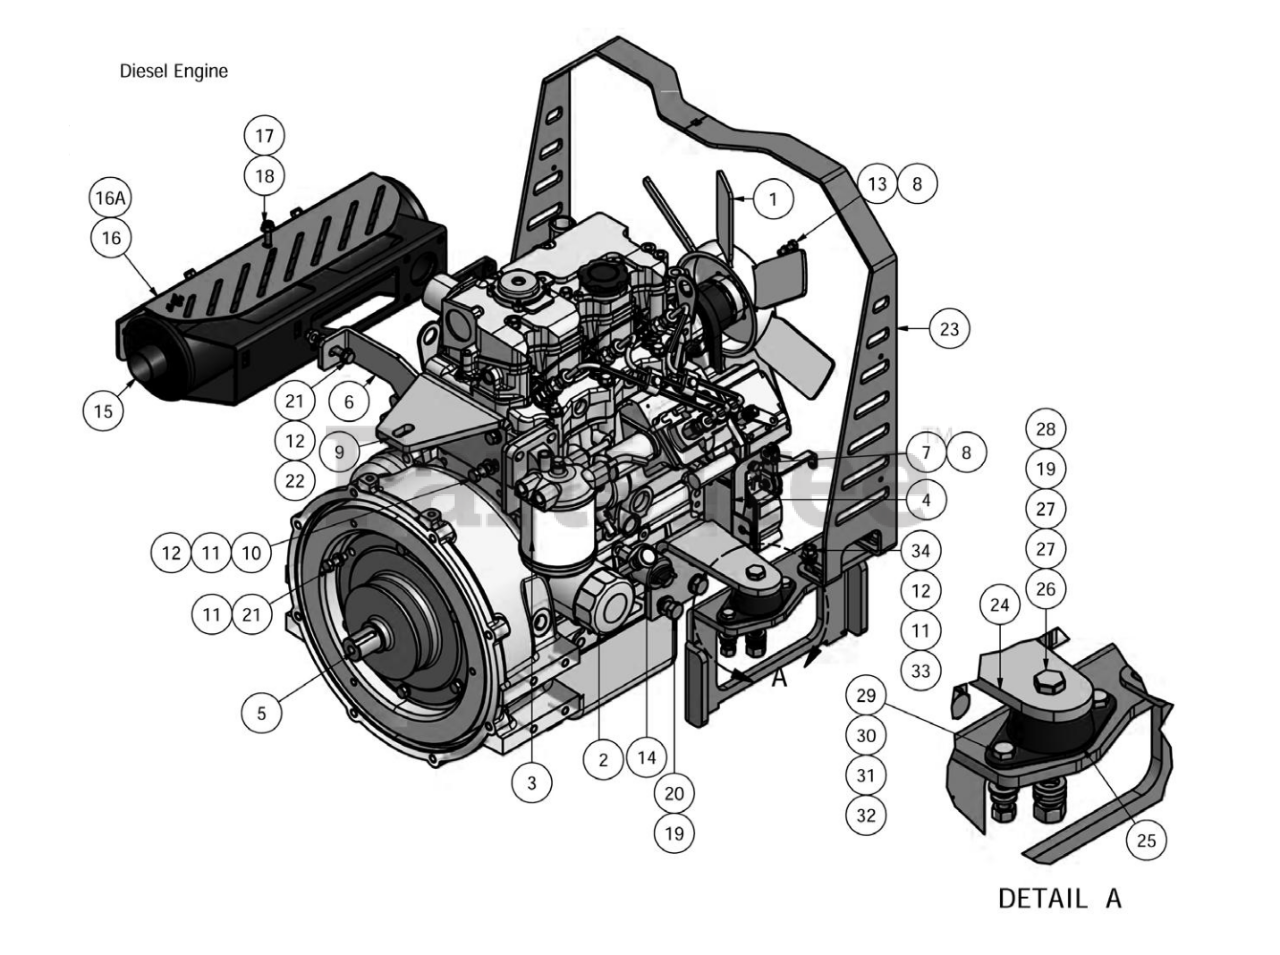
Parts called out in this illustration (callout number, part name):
1	Diesel Fan
2	Cat Oil Filter
3	Fuel Filter
4	Diesel Throttle Bracket (4 Tier)
5	Stub Shaft
6	Diesel Muffler Hanger Bracket
7	6 mm x 10 mm Hex Bolt
8	1/4" Lock Washer
9	Rear Motor Mount for Diesel
10	M8 x 1.25 x 25mm Hex Head Bolt
11	5/16" Lock Washer
12	5/16" Flat Washer
13	6mm x 20mm Bolt
14	Oil Pressure Guage with Sender
15	Diesel Muffler
16	Diesel Muffler Guard (28hp)
16A	Diesel Muffler Guard (35hp)
17	1/4" x 3/4" Set Screw
18	1/4" Flange Nut
19	1/2" Lock Washer
20	12mm Bolt-Diesel
21	5/16" x 1" Bolt
22	5/16-18 Nylock Flange Nut
23	Hood Holder Diesel
24	Diesel Motor Side Support
25	Rubber Isolator
26	1/2" x 3" Hex Bolt
27	1/2" Brass Washer
28	1/2" Hex Nut
29	3/8" x 1" Hex Bolt
30	3/8" Flat Washer
31	3/8" Lock Washer
32	3/8" Hex Nut
33	5/16" x 1 1/4" Hex Bolt
